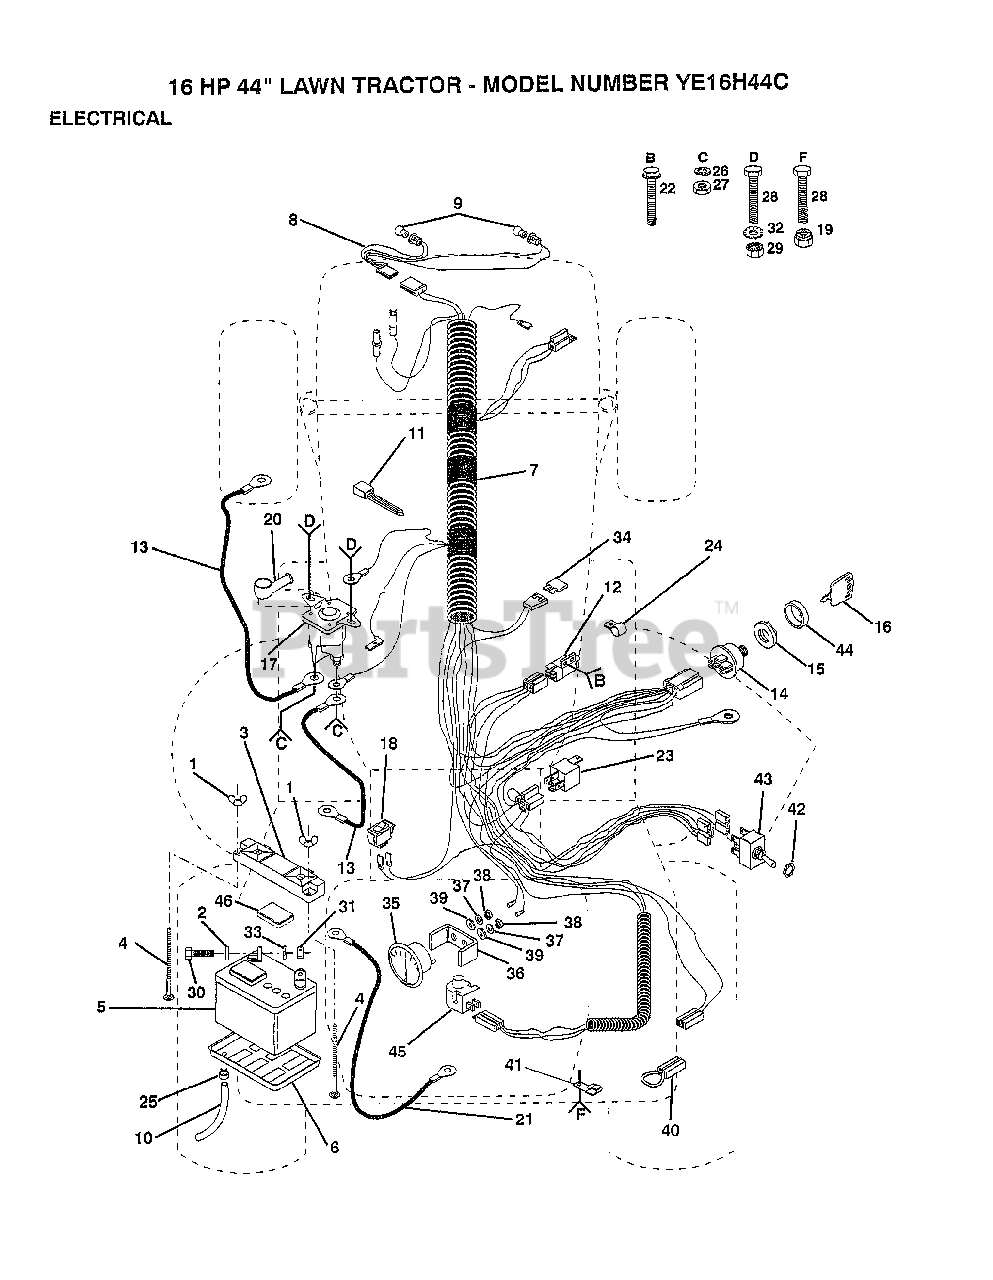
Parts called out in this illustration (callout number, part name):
2	WASHER
4	BOLT
6	"TRAY T, BATTERY"
7	"HARNESS,IGNITION"
12	SWITCH INTERLOCKT
15	NUT IGNITION
16	KEY
18	SWITCH LT
21	CABLE T
22	SCREW
23	RELAY ASSY T
24	CLIP T
25	HOSE CLAMP T
27	NUT
28	BOLT
29	NUT
30	BOLT LT
33	LOCKWASHER
34	FUSE HYT
35	AMMETER T
39	WASHER
41	CLIPT
42	HEX NUT T
45	SWITCH SEAT
46	"CAP,BATTERY "
